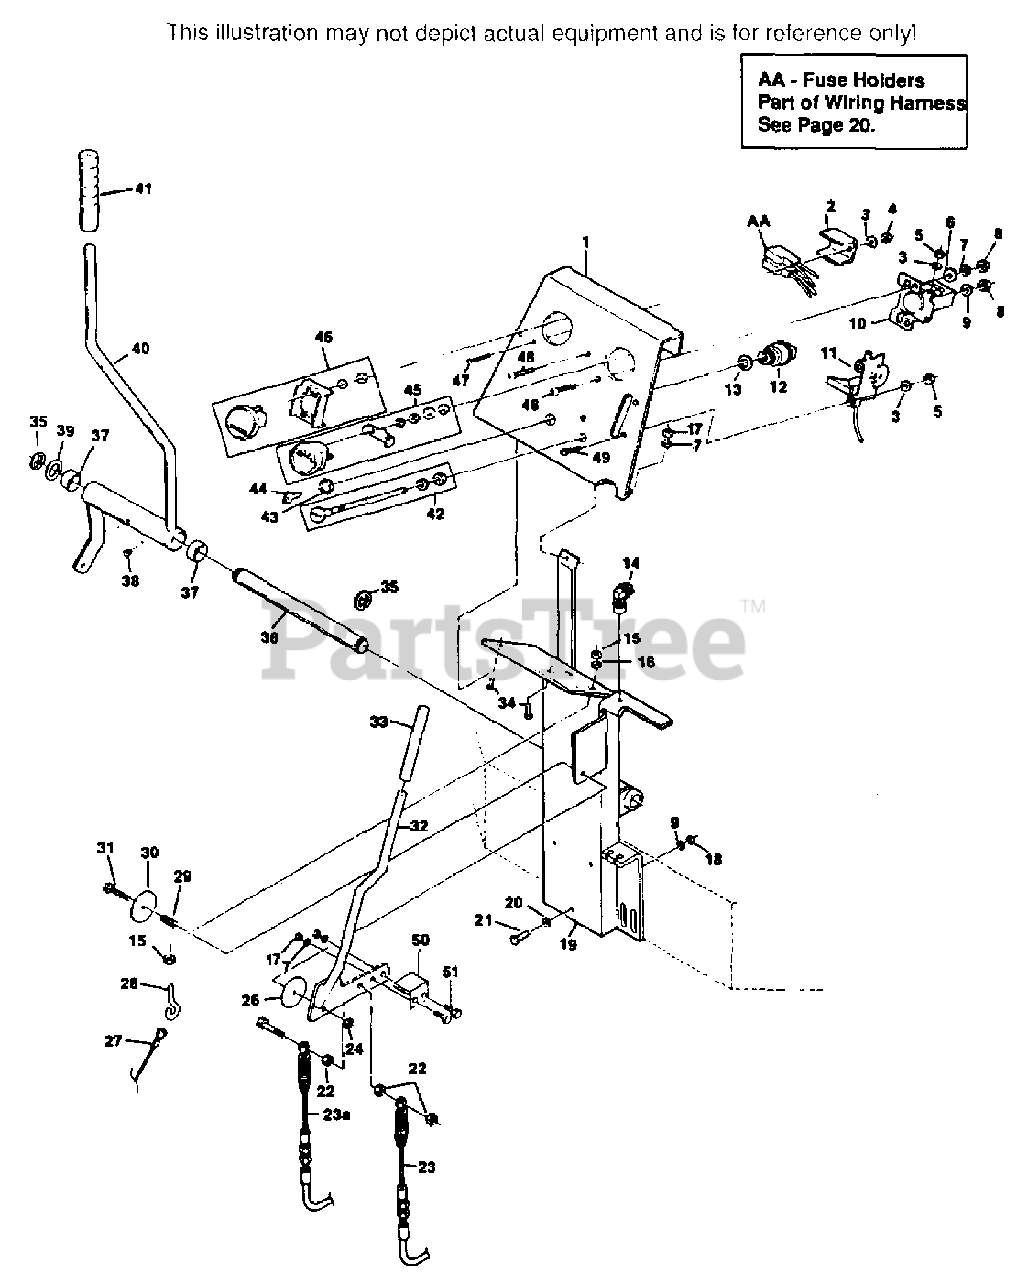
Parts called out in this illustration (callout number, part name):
1	INSTRUMENT PANEL(INCLUDES DECAL)
2	BRACKET, FUSE HOLDER
3	LOCKWASHER, #10 EXTERNAL TOOTH
4	HEX NUT, ELASTIC STOP LOCK #10-32
7	LOCKWASHER, 1/4 SPRING
9	LOCKWASHER, 5/16 SPRING
10	SOLENOID, STARTER
11	THROTTLE CONTROL
12	SWITCH, KEY
13	LOCKWASHER, 5/8 INTERNAL TOOTH
14	SWITCH, PARKING BRAKE
16	LOCKWASHER, 3/8 SPRING
19	CONSOLE SUPPORT
23	CABLE ASSY., PARKING BRAKE - RH
23A	CABLE ASSY., PARKING BRAKE - LH
24	HEX NUT, ELASTIC STOP LOCK 3/8-16
26	FLAT WASHER, 3/8 X 1-1/2 X 16 GA.
27	CABLE, WINCH
28	EYE BOLT, 3/8-16 X 2
29	SPRING, SHIFT LEVER
30	FLAT WASHER, 3/8 X 1-1/2 X 16 GA.
32	HANDLE, PARKING BRAKE
33	GRIP, PARKING BRAKE
35	RETAINING RING, 3/4 "E"
36	SHAFT, BELLCRANK PIVOT
37	BRONZE BUSHING
38	GREASE FITTING
39	FLAT WASHER, 3/4(49/64 X 1-1/4 X 16 GA.)
40	BELLCRANK, BELT CLUTCH
41	GRIP, CLUTCH LEVER
42	CHOKE CONTROL(INCLUDES HARDWARE)
43	HEX NUT, 5/8-11
44	KEY, IGNITION
45	AMMETER(INCLUDES HARDWARE)
46	HOUR METER(INCLUDES HARDWARE)
50	BRKT, PARKING BRAKE SWITCH ACTUATING
